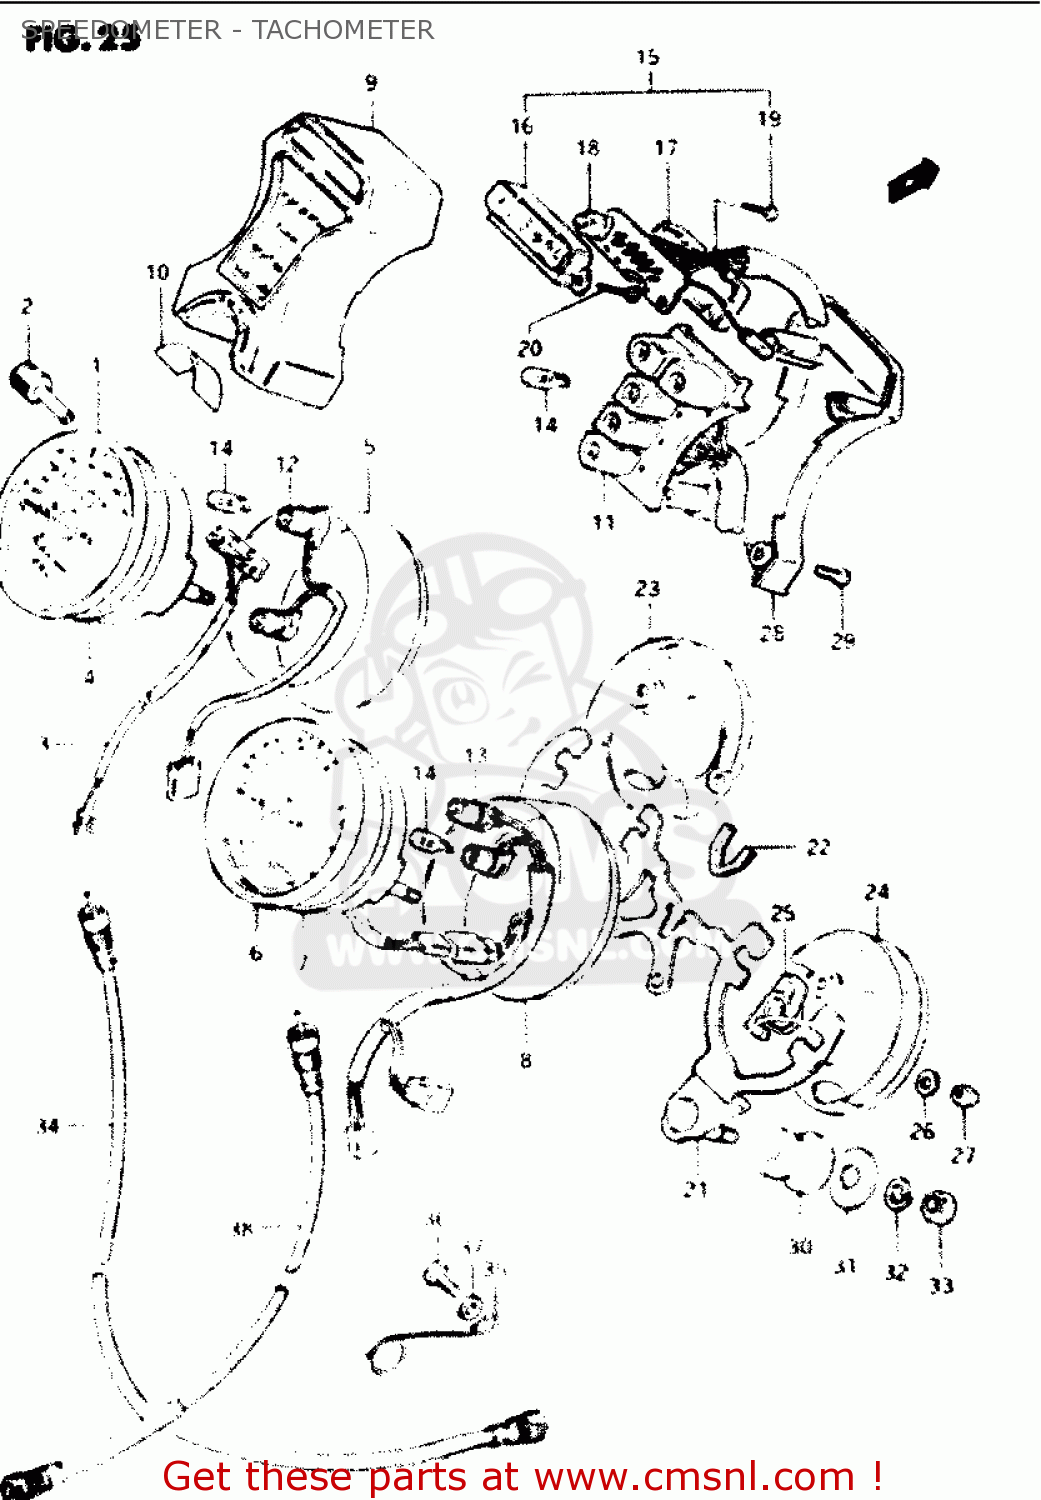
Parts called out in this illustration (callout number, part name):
1	SPEEDOMETER (KILO)
2	KNOB,TRIP
3	WIRE,LEAD SWITCH
4	CUSHION,METER
5	COVER,SPEEDOMETER
6	TACHOMETER
7	CUSHION,METER
8	COVER,TACHOMETER
9	CASE,PILOT BOX
10	SEAL,IGNITION SWITCH
11	SOCKET,PILOT BOX
12	SOCKET,SPEEDOMETER
13	SOCKET,TACHOMETER
14	BULB(12V3.4W,T10)
15	INDICATOR ASSEMBLY,GEAR POSITION
16	CASE,GEAR INDICATOR
17	COVER,LWR
18	BULB(14V1.12W,BQ041-32503B)
19	SCREW,GEAR INDICATOR
20	SCREW
21	BRACKET,COMBINATION METER
22	BRACKET,COVER
23	COVER,METER,UNDER
24	COVER,TACHOMETER,UNDER
25	CUSHION
26	WASHER
27	NUT
28	COVER,PILOT BOX LWR
29	SCREW,PILOT BULB CASE
30	CUSHION,METER BRACKET
31	WASHER (8.5X20X1.6)
32	WASHER,LOCK,8.
33	NUT
34	CABLE ASSEMBLY,SPEEDOMETER
35	CLAMP,SPEEDOMETER CABLE
36	BOLT, UPPER
37	WASHER
38	CABLE ASSEMBLY,TACHOMETER
